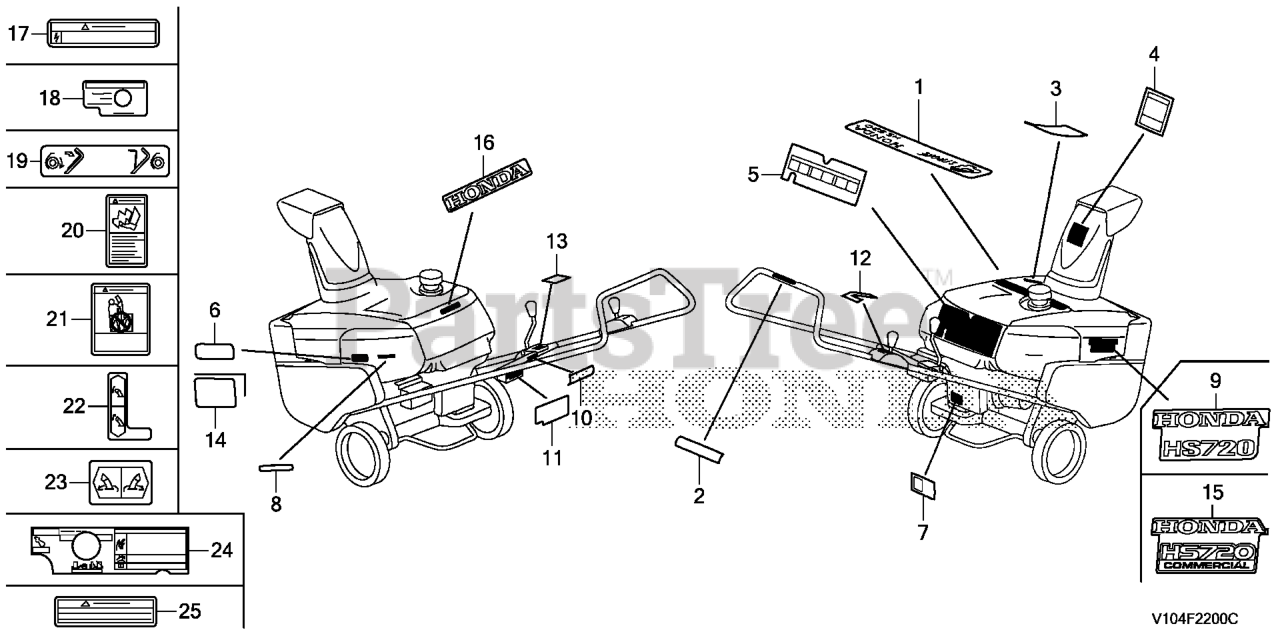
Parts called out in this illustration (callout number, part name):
2	MARK, CLUTCH OPERATION (ENGLISH)
3	MARK, DANGER (ENGLISH)
4	MARK, DISCHARGE DANGER (ENGLISH)
5	MARK, CONTROL OPERATION (ENGLISH)
7	MARK, OIL CAUTION (PICTOGRAPH)
9	MARK, EMBLEM (HS720)
12	MARK, CHUTE GUIDE (ENGLISH)
13	MARK, CHUTE CONTROL (ENGLISH)
14	MARK, EX. CAUTION (ENGLISH)
16	MARK, HONDA
